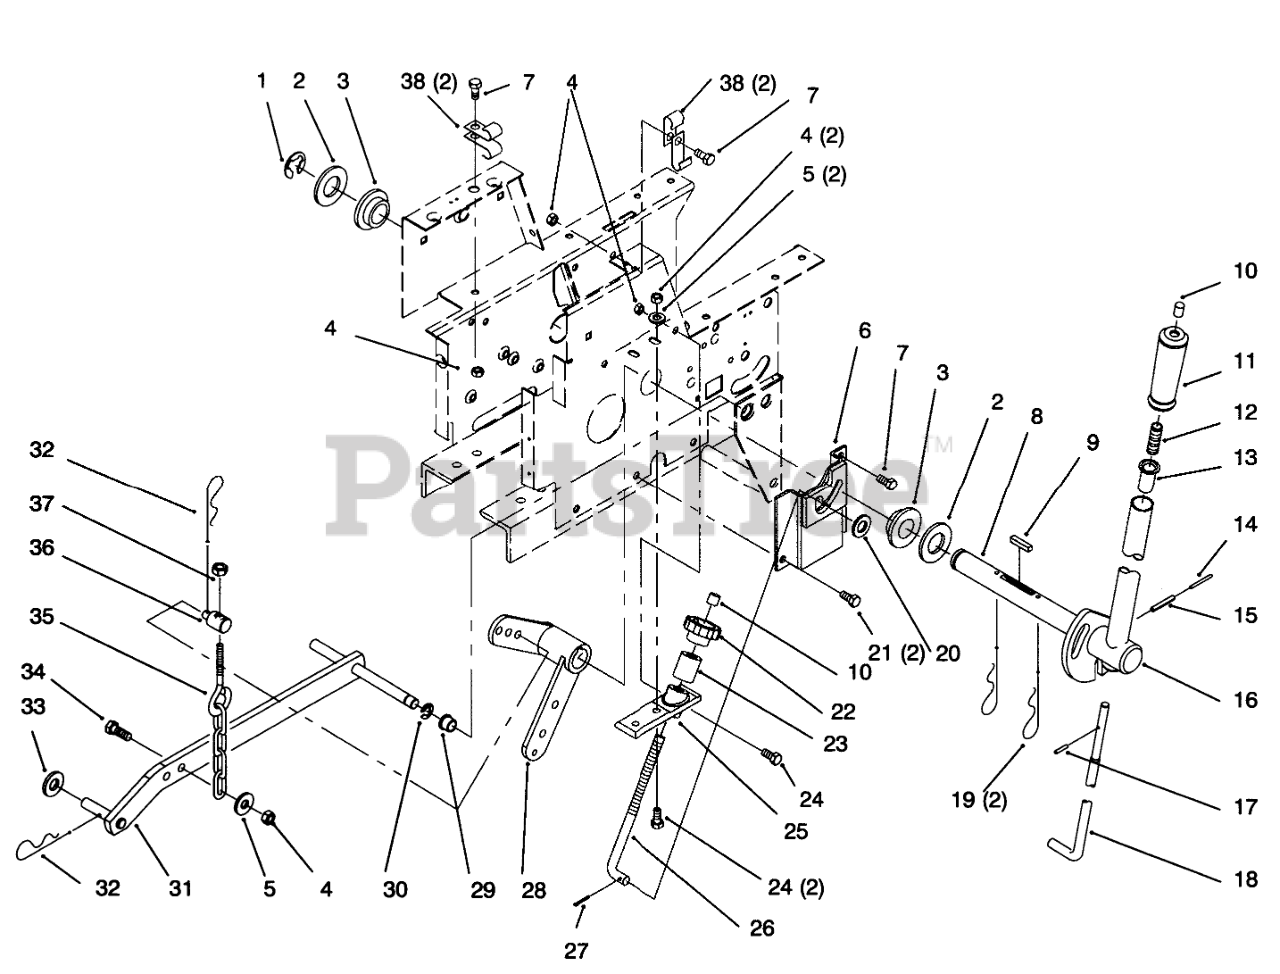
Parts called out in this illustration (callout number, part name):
1	RING-RETAINING
2	WASHER-FLAT
3	BEARING-FLANGE
4	NUT-LOCK, NI
5	WASHER-PLAIN
6	Latch Bracket
7	Bolt
8	SHAFT-LIFT LEVER
9	KEY-SQUARE
10	CAP-ROD, PLUNGER
11	GRIP-HANDLE
12	SPRING-COMPRESSION
13	RETAINER-SPRING
14	PIN-SPRING
15	PIN-ROLL
16	Lift Lever
17	PIN-SPIROL
18	ROD-LATCH LIFT
19	PIN-HAIR
21	WASHER-FLAT
21	SCREW-SELF TAP
22	KNOB-LIFT CONTROL
23	Sleeve
24	SCREW-HH
25	Casting
26	ROD-HEIGHT CONTROL
27	PIN-COTTER
28	LIFT LEVER ASM
29	BUSHING
30	RING-RETAINING, EXTERNAL
31	Bar-Lift
32	PIN-HAIR
33	WASHER-FLAT
34	SCREW-HH
35	CHAIN-LIFT
36	TRUNNION-LIFT
37	NUT-LOCK, NI
38	CLIP
39	SCREW-HH
